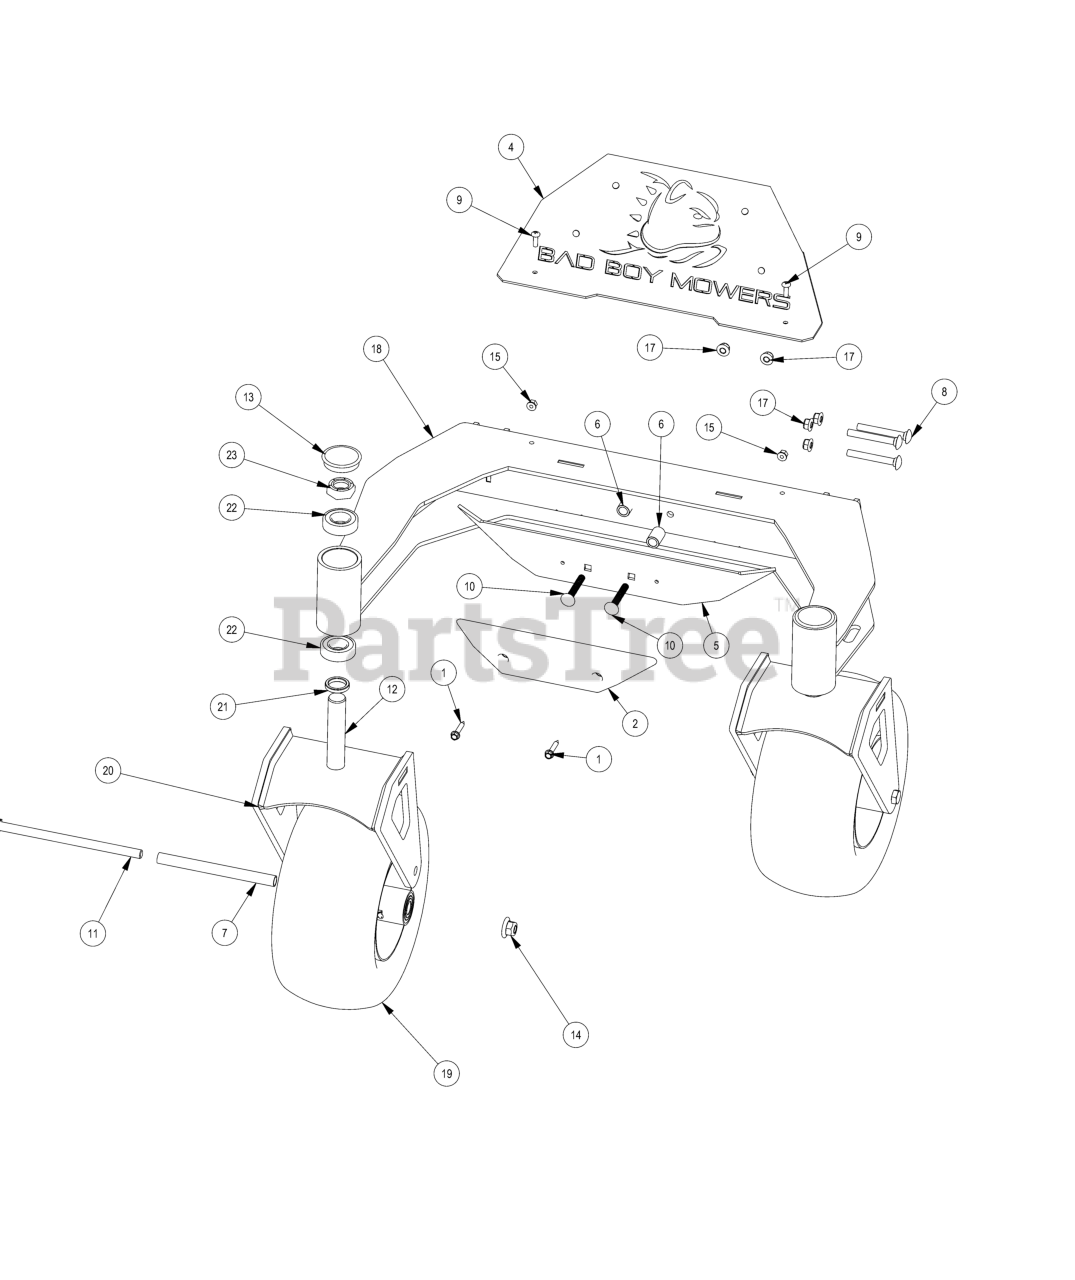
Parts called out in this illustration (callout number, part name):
1	1/4-14 X 1-1/2 HEX WASHER UNSLOT TEK/3 ZINC
2	Bumper EZT
3	Exhaust Backer Plate 2019 Stand On
4	Exhaust Shield Plate 2019 Stand On
5	2019 Stand On Front Bumper Plate
7	Front Wheel Spanner
8	3/8-16 X 3 CARRIAGE BOLT ZINC GR5
9	1/4"-20 x 3/4 Black Oxide 18-8 Stainless Pan Head
10	3/8" x 2 1/2" Carriage Bolt
11	1/2-13 X 8-1/2 HEX CAP SCREW (GR.5) ZINC
12	1"-14 X 5 HEX CAP SCREW (GR.8) ZINC YELLOW
13	2017 Bearing Cover
14	1/2-13 NYLON INSERT FLANGE LOCKNUT ZINC
15	1/4-20 Nylon Insert flange Nut
16	3/16" Diameter Black Rivet, for 0.1260"-0.25" Material Thick
17	3/8" Nylock Flange Nut
18	2023 36 Stand-On Front End Weldment
19	13x6.50-6 Black No Flat Assembly
20	2019 Stand-on Front Fork Weldment
21	Spacer, 1x1.375x.25
22	1641 BEARING W/2 CONTACT RUBBER SEALS
23	1" Fine Thread 1/2 Nylock Nut
